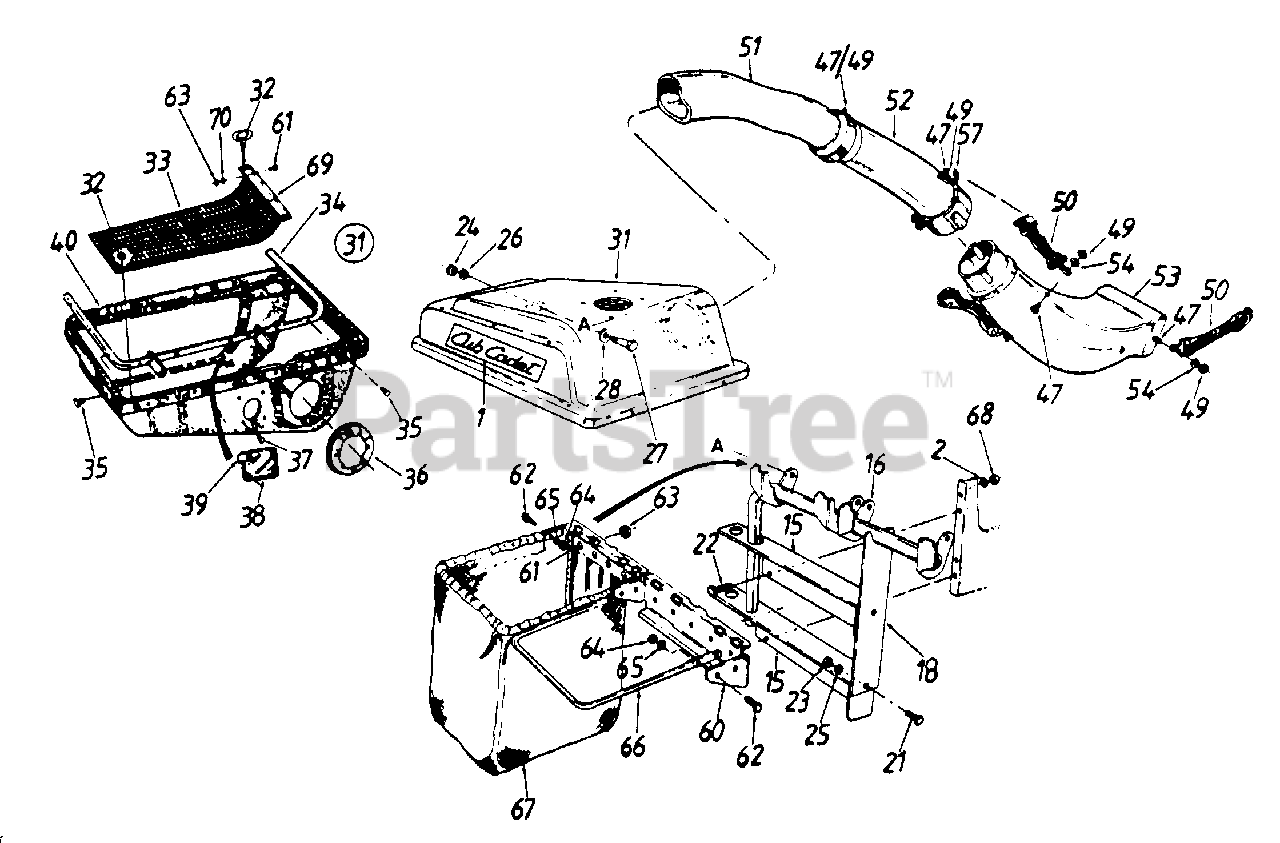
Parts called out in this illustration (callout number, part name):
1	PLATE-NAME-CUB CADET-BAGGER
2	WASHER-FL-.266X.625
15	BRACKET-MTG
16	TUBE ASSY-SUPPORT
18	BRACKET-SUPPORT
21	SCREW-HEX 5/16-18 X .75
22	SCREW-1/4-20 X .62
23	NUT-HEX 5/16-18
24	NUT-HEX 3/8-16
25	WASHER-LOCK-5/16
26	WASHER-LOCK-3/8
27	SCREW-SHLD
28	WASHER-BELL .505 ID X 1.00 OD
31	COVER ASSY-GRASS
32	FASTENER-TWIST
33	SCREEN ASSY
35	SCREW-HEX TAP
36	SEAL
37	SCREW-TRUSS MACH
38	PLATE-PLASTIC
39	NUT-SPEED
40	COVER ASSY-GRASS
47	SCREW-HEX 1/4-20 X .50
49	NUT-INS LOCK 1/4-20
50	STRAP ASSY-RETAINER
51	ELBOW-CATCHER
52	TUBE-CATCHER
53	DISCHARGE CHUTE - W/CUTOUT
54	WASHER-SPRING.270 ID X.51 OD X.030
57	BRACKET-HOOK RETAIN
61	SCREW-TRUSS MACH #10-24 X .50
62	SCREW-HEX 1/4-28 X .75
63	NUT-SEMS 10-24
64	NUT-HEX 1/4-28
65	LOCK WASHER 1/4 DIA
67	BAG-GRASS
68	NUT-HEX 1/4-20 GR 5
69	SCREEN ASSY
70	WASHER-FL .192 X .625 X .057
